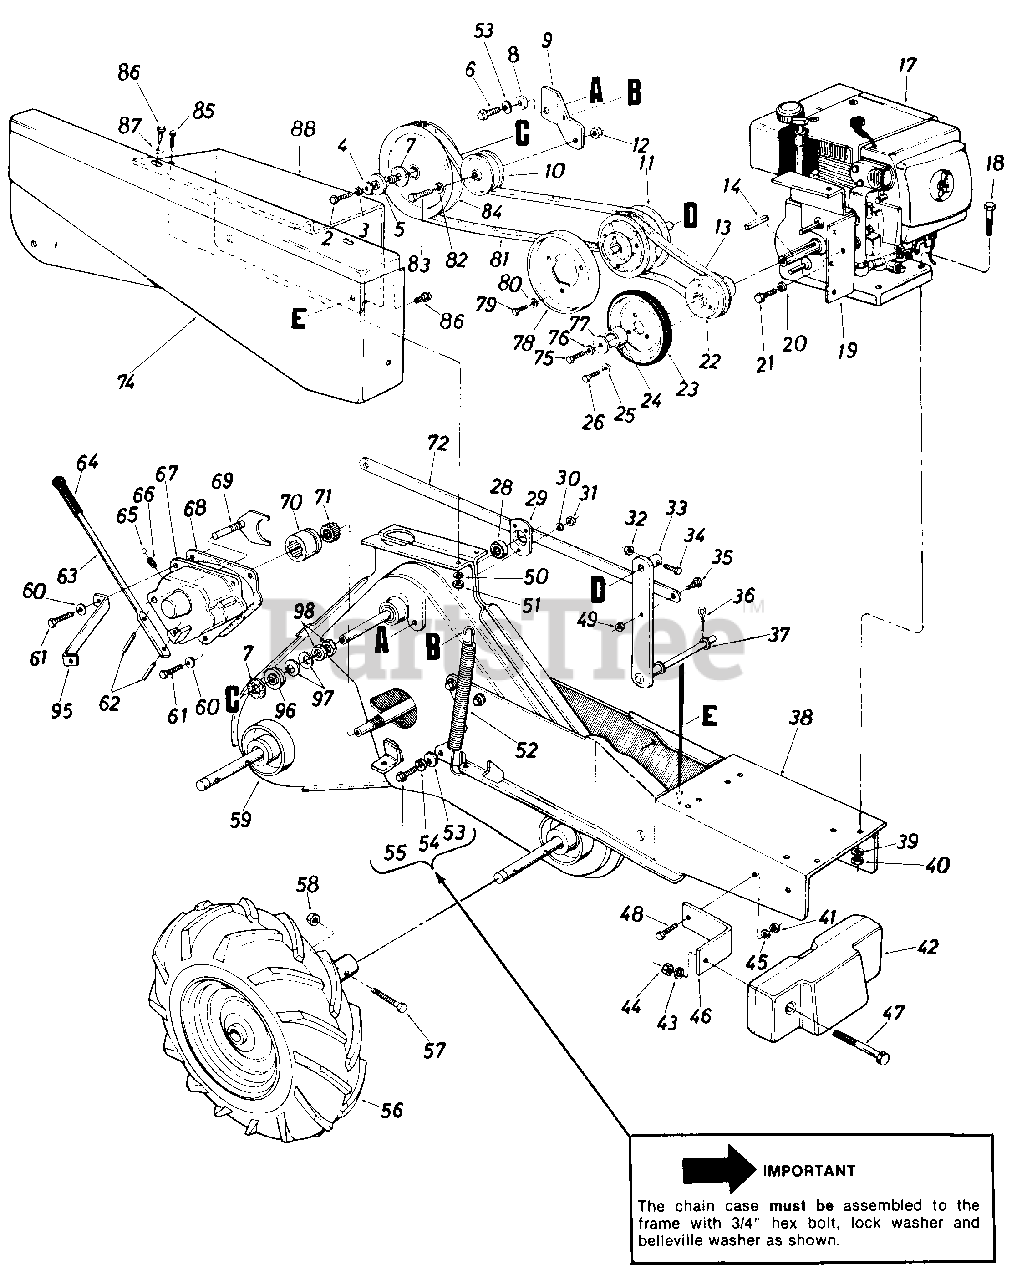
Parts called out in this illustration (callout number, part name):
2	SCREW-HEX CL 5/16-24X1.5
3	WASHER-LOCK-5/16
4	WASHER-FL-.312 X 1.125 X .125
5	HUB & DISC ASSY
6	SCREW 3/8-24 X 1.25 GR5
7	PAD-FRICTION
8	SPACER-SHLD
9	BRACKET-IDLER
10	PULLEY-IDLER-FLAT W/FLANGES
11	PULLEY-VAR SP
12	NUT-HEX INS L-3/8-16
13	BELT-V 5/8 X 27
14	KEY-SQ 1/4 X 2.00
18	SCREW-HEX 5/16-18 X 1.75
19	BRACKET ASSY-BELT COVER
20	WASHER-INTERN L-1/2
21	SCREW-HEX 1/2/20 X .75 SPEC
23	WHEEL ASSY-FRICTION
24	SPACER-ENGINE PULLEY
25	WASHER-LOCK-5/16
26	SCREW-HEX 5/16-18 X .52
28	BEARING-BALL
29	BEARING-BALL
30	LOCK WASHER 1/4 DIA
31	NUT-HEX 1/4-28
32	NUT-INS LOCK 1/4-20
33	BRACKET ASSY
34	SCREW-HEX 1/4-20 X 1.25
35	SCREW-SHLD
36	PIN-COTTER-1/8 DIA X 1.00
37	WASHER-FL
38	FRAME ASSY
39	WASHER-LOCK-5/16
40	NUT-HEX 5/16-18
41	NUT-HEX INS L 3/8 X 24
42	COUNTERWEIGHT
43	WASHER-FL
44	NUT-HEX 1/2-13
45	WASHER-LOCK-3/8
46	BRACKET-COUNTERWEIGHT
47	SCREW-HEX 1/2-13 X 4.50
48	BOLT-3/8 NF X 1"GR5
49	NUT-HEX INS L-3/8-16
50	LOCK WASHER 1/4 DIA
51	NUT-HEX 1/4-28
52	EXTENSION SPRING
53	WASHER-BELL .400 ID X .88 X .060
54	WASHER-LOCK-3/8
55	SCREW-HEX WASH SF TAPP 3/8 X 3/4
56	WHEEL ASSY W/TIRE-RH
57	SCREW 3/8-24X1.25 GR5
58	NUT-HEX INS L-3/8-24
59	CHAIN CASE ASSY-COMP
60	WASHER-LOCK-5/16
61	SCREW-HEX WASH SF TAPP
62	PIN-SPRING SPIR 3/16 X 1.00
65	BALL-DETENT
66	SPRING-DETENT FOOTE #333-19
67	HOUSING-RH
68	NUT-HEX CENTER L-#10-32
69	YOKE-SHIFT-RH
71	DOG-DRIVER
72	STRIP-CONTROL
74	COVER ASSY-BELT
75	SCREW-HEX 7/16-20 X 2.25
76	WASHER-LOCK-7/16
77	WASHER-FL - .440 X1.375 X .148
78	DISC-FRICTION
79	SCREW-HEX 1/4-28 X .50
80	LOCK WASHER 1/4 DIA
81	BELT-V 5/8 X 51
82	WASHER-LOCK-3/8
83	SCREW-HEX 3/8-16 X 1.50
85	SCREW-HEX 1/4-28 X .62
86	SCREW-HEX WASH SF TAPP
87	WASHER-FL-.28 ID X .74 OD X .063
88	SHROUD-BELT COVER
95	BRACE-BELT COVER
96	DISC-FLOATING
97	WASHER-SPRING BELL
98	NUT-HEX JAM-SPECIAL
